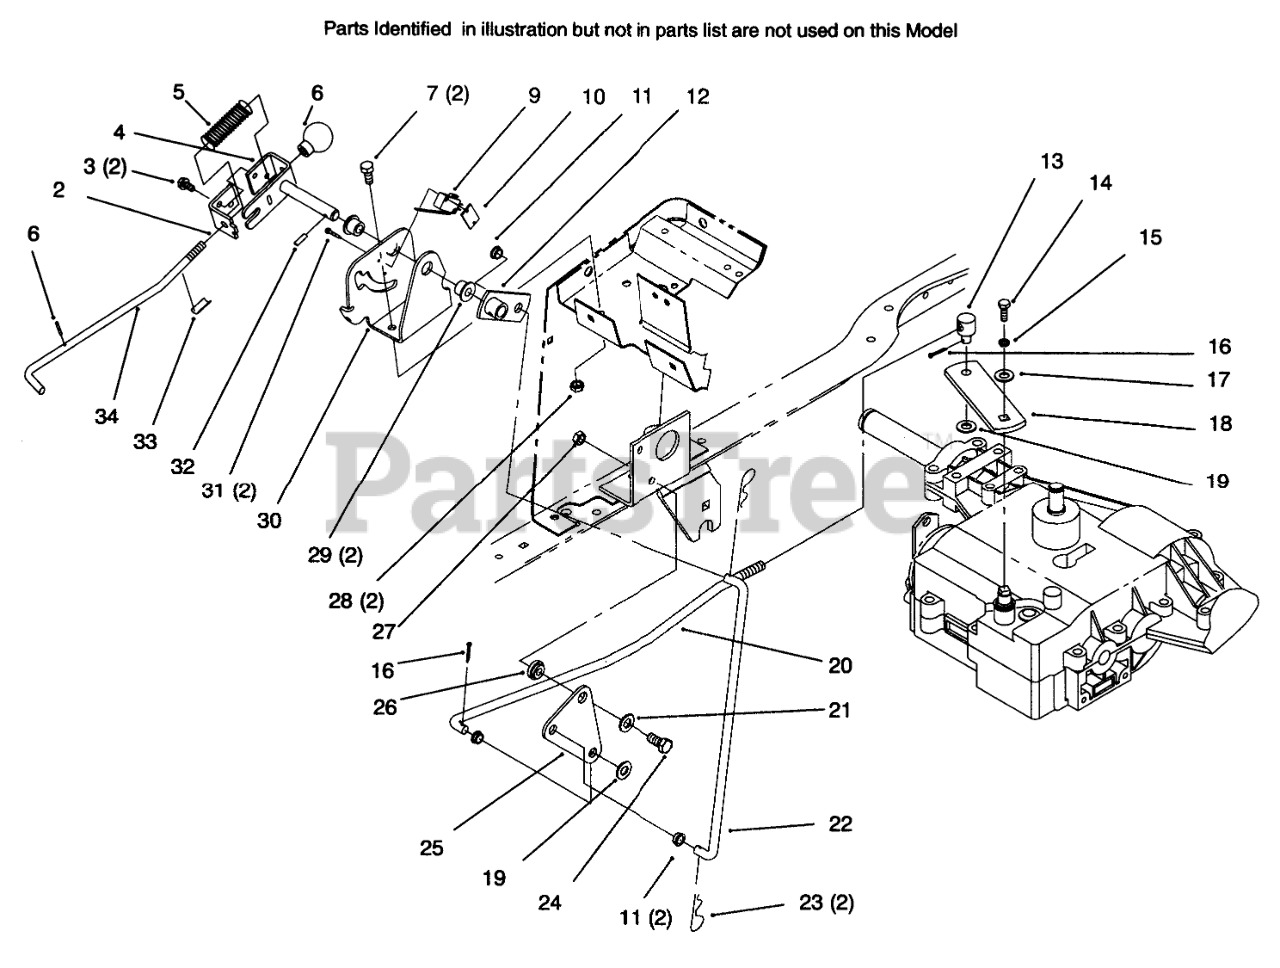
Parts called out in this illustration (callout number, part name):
2	BRACKET - SHAFT
3	SCREW-HWH
4	PIVOT ARM WA PLATED
5	SPRING-COMPRESSION
7	SCREW-HH
9	SWITCH - CLUTCH
10	NUT-SPEED
11	BRG - SHIFT LINKAGE
12	TUBE-LINKAGE
13	TRUNNION
14	SCREW-HH
15	WASHER-LOCK
16	PIN-COTTER
17	SPACER
18	BRK-TRASXL SHI
19	WASHER-FLAT
20	ROD - TRANSAXLE SHIFT
21	WASHER-FLAT
22	ROD - LINKAGE
23	PIN-COTTER
24	SCREW-HH
25	BRACKET - PIVOT
26	BUSHING
27	NUT-LOCK, NI
28	NUT-LOCK, NI
29	BUSHING
30	BRKT-PIVOT MTG (BLACK)
31	SCREW-HH
32	PIN-ROLL, SLOTTED
33	DECAL - REVERSE GEAR
34	ROD - SHIFT
